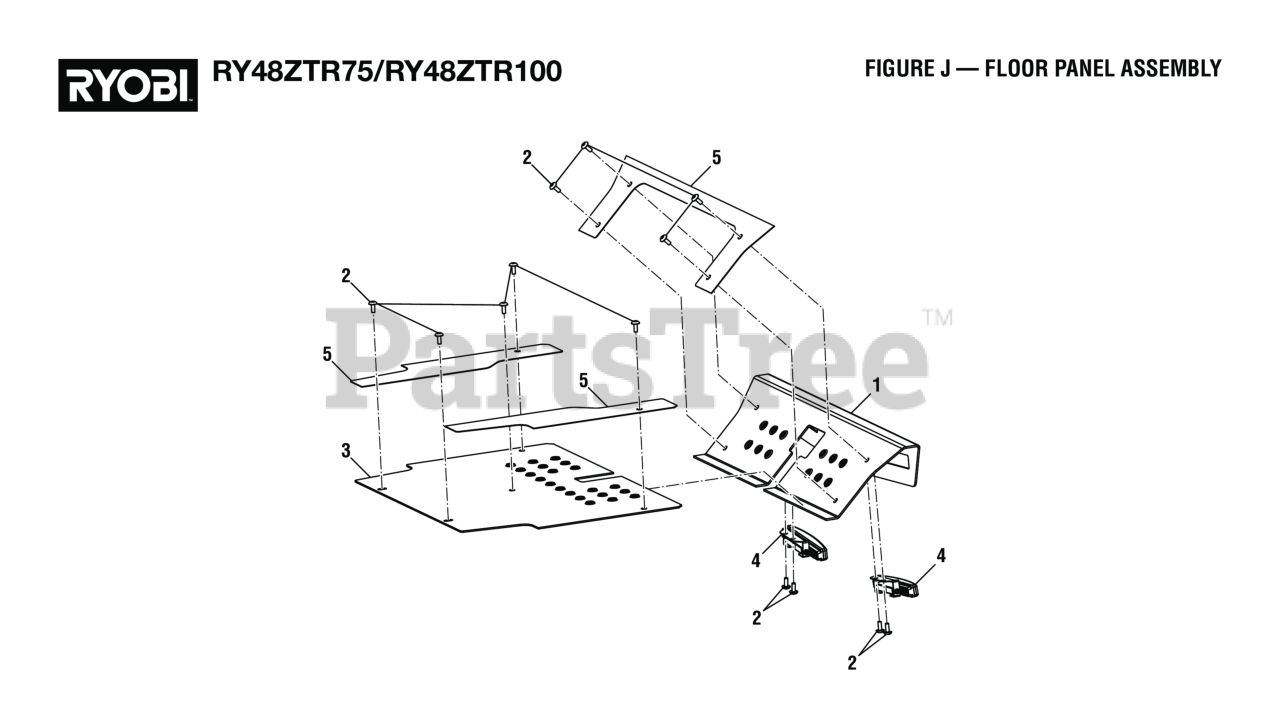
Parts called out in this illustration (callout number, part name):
1	Foot Rest Plate
2	Screw (M6 x 10 mm, Soc. Button Hd.)
3	Floor Plate
4	Light Assembly
5	Anti Slip Decal Package
